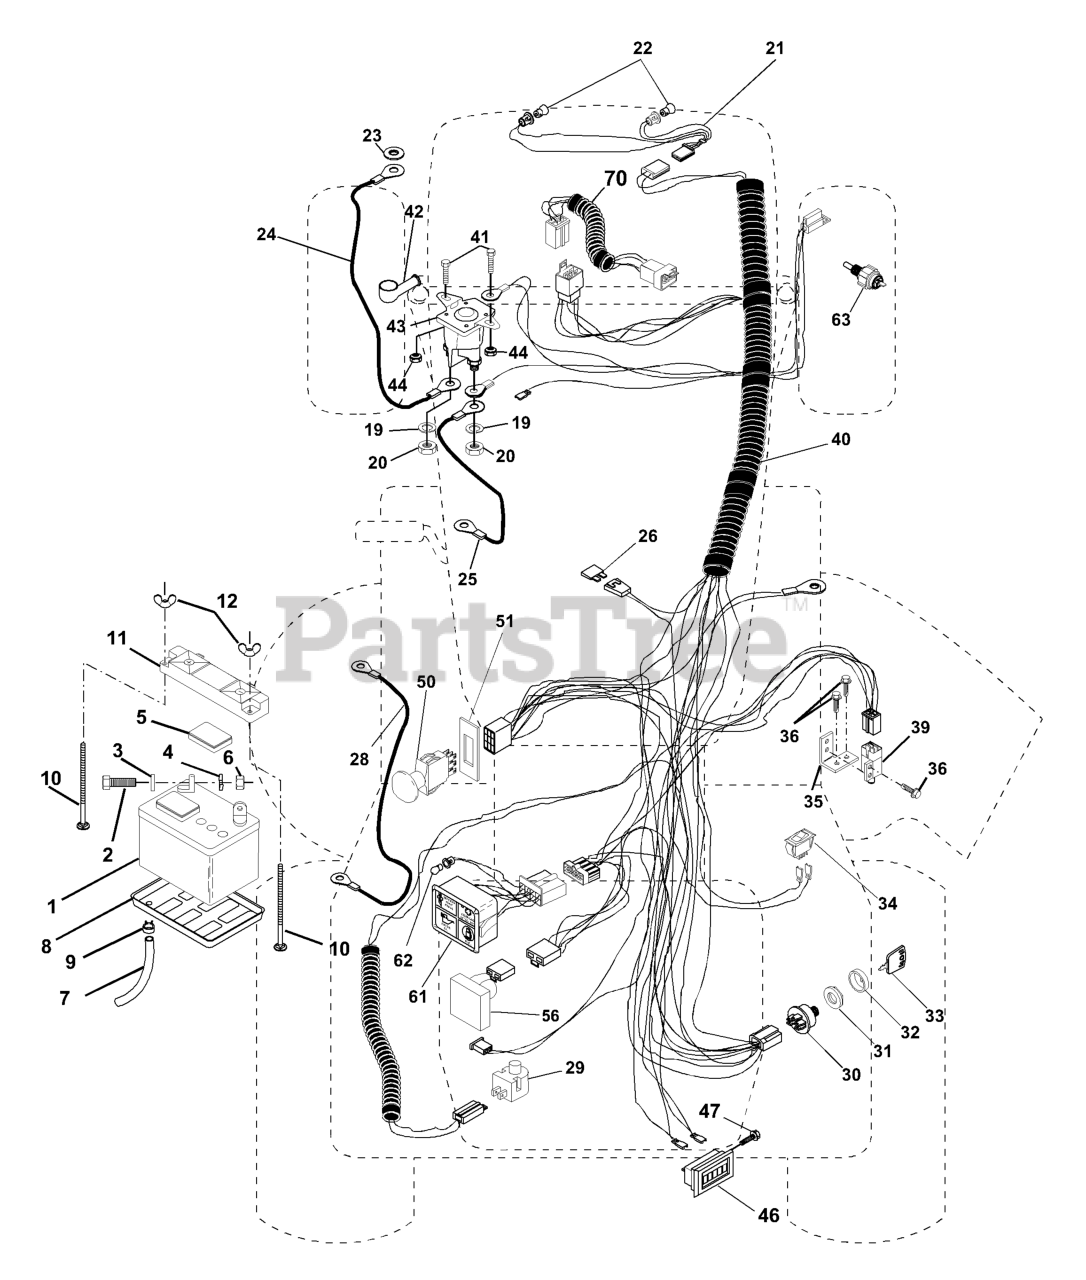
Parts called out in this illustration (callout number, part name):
1	BATTERY
2	BOLT.HEX.1/4.X.3/4.DICHROMATE
3	WASHER
4	LOCKWASHER
5	CAP BATTERY NLA
6	NUT
7	PLASTIC TUBE
8	BATTERY TRAY T
9	HOSE CLAMP T
11	TERMINAL GRD YTV
12	WING NUT
19	LOCKWASHER
20	NUT
21	HARNESS LIGHT SOCKET
23	Washer, Lock, Internal Tooth 1/4
24	CABLE-BATTERY YTV
25	BATTERY CABLE GT
28	CABLE T
29	RP.SWITCH.PLUNGER.NC.GRAY
30	IGNITION SWITCH
31	NUT, IGNITION
32	COVER SWITCH KEY
33	KEY MLD GEN DELTA
35	BRACKET LT
39	SWITCH INTERLOCKT
40	IGNITION HARNESS
41	BOLT
42	TERMINAL COVER
43	SOLENOID
44	Nut, Hex, Keps 1/4-20
46	HOUR METER T
47	Screw #10-24 x 1/2
50	SWITCH-PTO
51	FRAME RETAINING RING
56	SENSOR LOW VOLTAGE
61	LIGHT PACKAGE
62	BULB LIGHT T
70	ENGINE HARNESS
